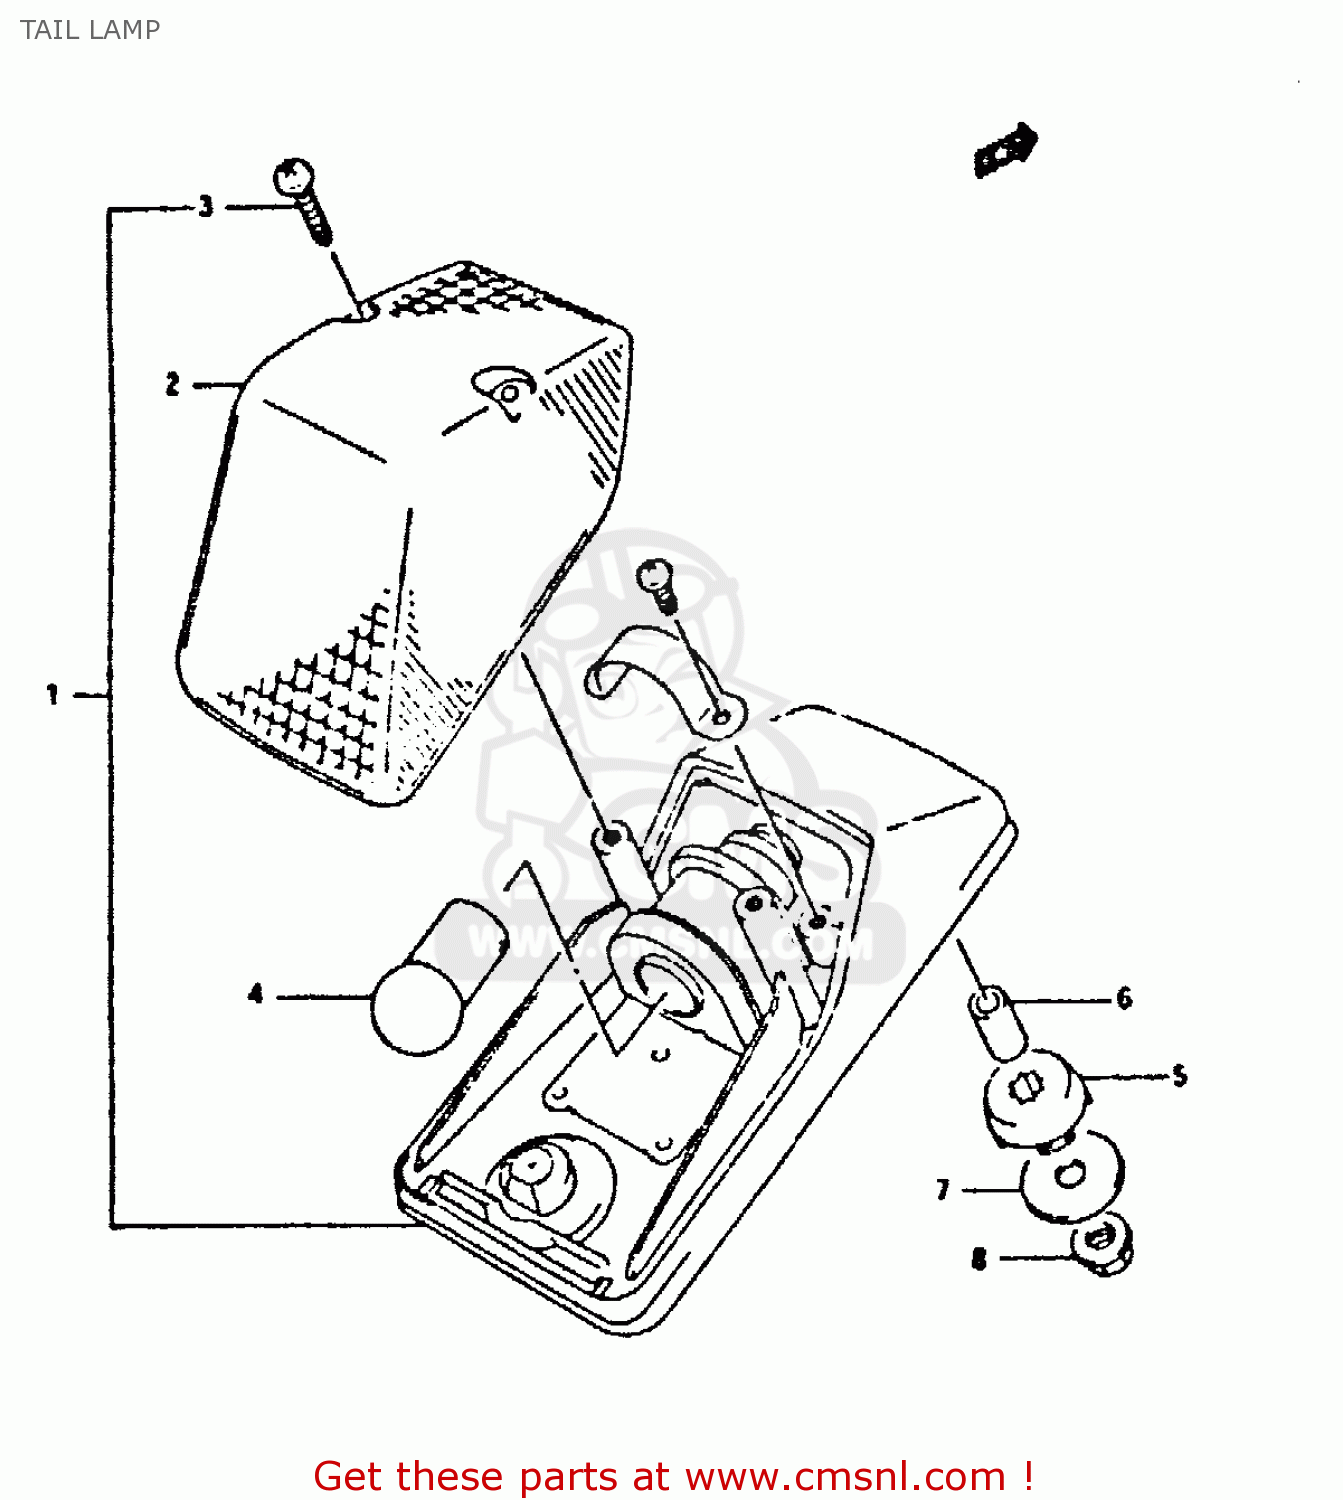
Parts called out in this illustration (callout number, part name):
1	LAMP ASSY,TAIL
2	LENS
3	SCREW
4	BULB(12V5W,BF150-40160A)
5	CUSHION
6	SPACER(6.4X9.2X12)
7	WASHER
8	NUT
